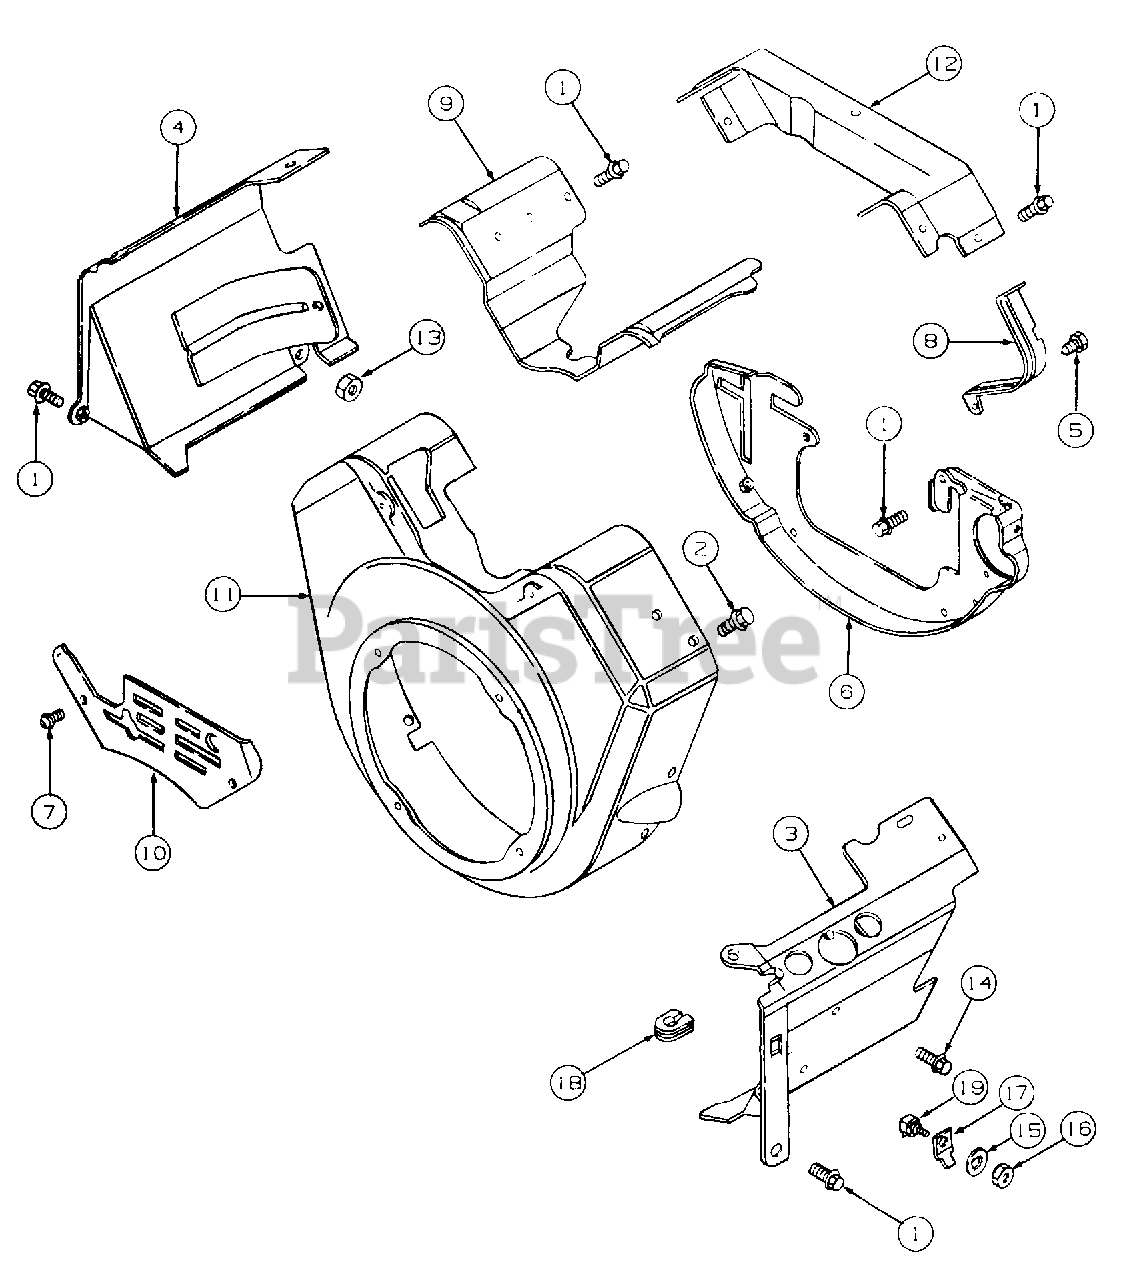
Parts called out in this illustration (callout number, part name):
1	Screw, Sems
2	Screw, Sems
3	Cover (Cylinder #1)
4	Cover (Cylinder #2)
5	Screw, Sems
6	Plate, Back
7	Screw, Sems
10	Cover, Carburetor
11	Housing, Blower
12	Cover, Valley Extension
13	Nut, Hex
14	Screw, Mtg
15	Washer, Lock, Internal Tooth
17	Terminal, Ground
18	Grommet, Cable
19	Insulator Assy
